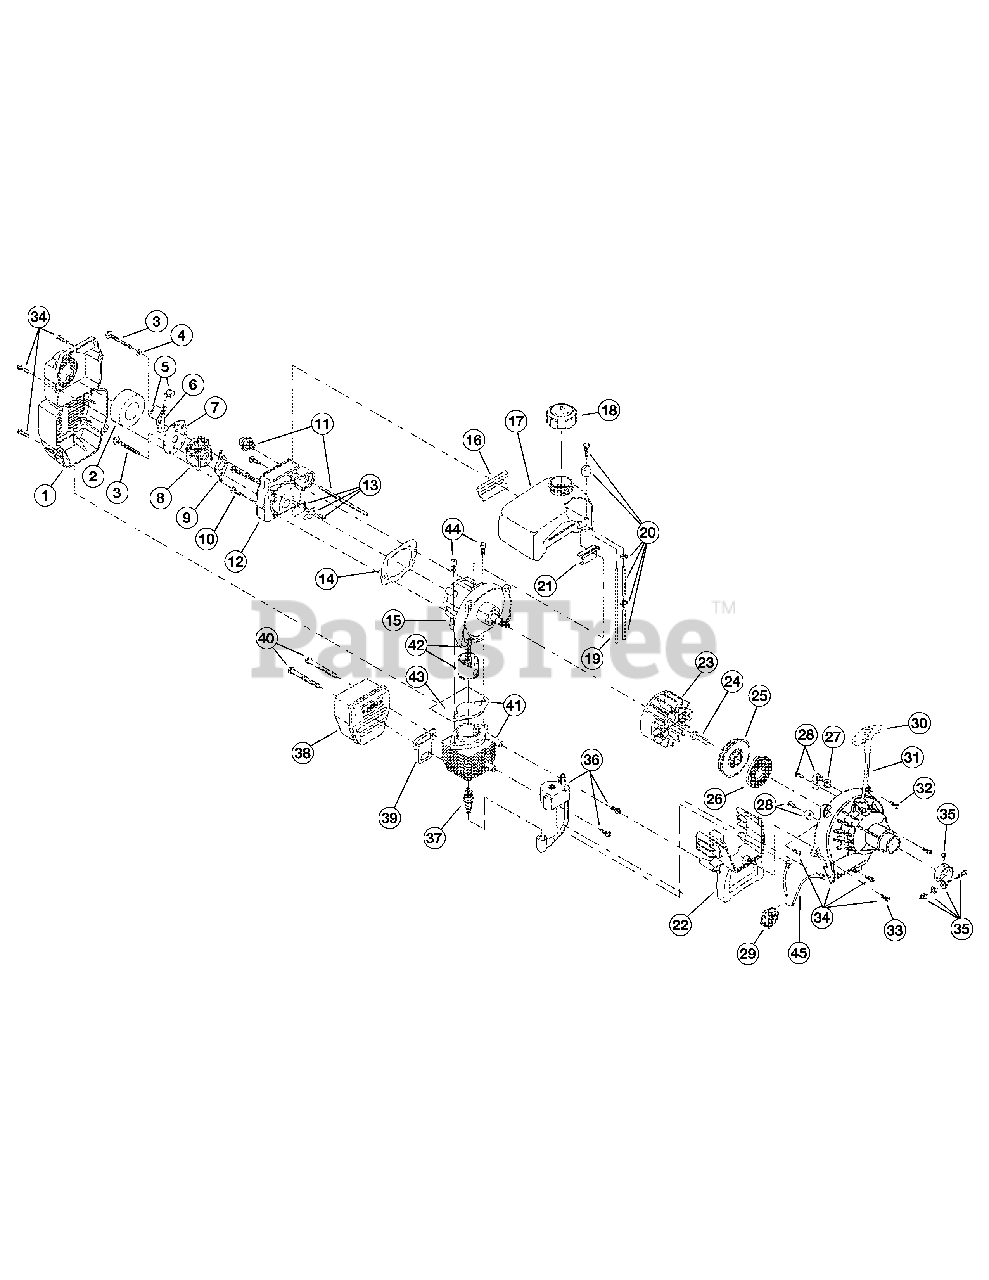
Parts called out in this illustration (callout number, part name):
1	Air Cleaner Cover Assembly (includes 2 & 34)
2	Air Cleaner Filter
3	Carburetor Mounting Screw Assembly
4	Wavey Washer
5	Choke Knob Assembly
6	Choke Lever Assembly (includes 5)
7	Choke Plate Assembly (includes 6)
8	Carburetor Assembly (includes 9, 19 & 20)
9	Carburetor Gasket
10	Carb Mount Screw
11	Primer and Hose Assembly
12	Carb Mount Assembly (includes 10 & 13)
13	Reed Assembly
14	Carburetor Mount Gasket
15	Crank Case Service Assembly (includes 10)
16	Rear Mounting Pad
17	Fuel Tank Assembly (includes 19-20)
18	Fuel Cap Assembly
19	Fuel Return Line
20	Fuel Line Assembly
21	Front Mounting Pad
22	Shroud Extension and Stand
23	Flywheel Assembly
25	Recoil Pulley
26	Recoil Spring
27	Rope Guide
28	Pulley Retainer Assembly
29	Momentary Switch
30	Pull Handle
32	Housing Screw
33	Cover Screw
34	Starter Housing Assembly (includes 25-28, 30-33)
35	Upper Clamp Assembly
36	Module Assembly MA-57 792-10527A (mfg date 6/21/05 and prior)
36	Module Assembly M-56 7181B (mfg date 6/21/05 and after)
37	Spark Plug
38	Muffler Assembly (includes 39 & 40)
39	Exhaust Gasket
40	Muffler Mounting Bolts
41	Cylinder Assembly (includes 43)
42	Piston and Rod Assembly
43	Cylinder Gasket
44	Cylinder Bolt
45	Lead Wires
